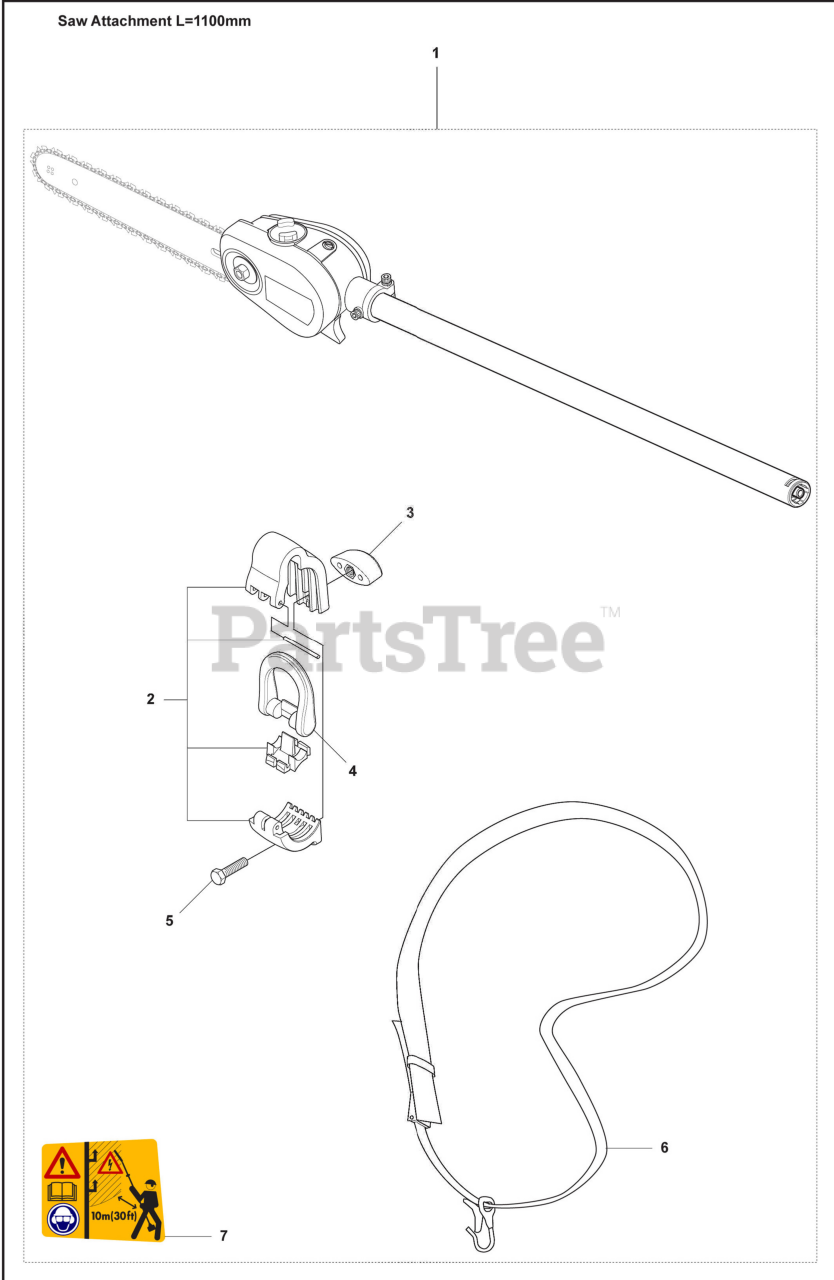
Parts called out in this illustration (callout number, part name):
1	DX POLE SAW ATTACHMEN
1	Dx Pole Saw Attachment
2	Hanging Bracket
5	Screw, M6S 5 X 20
6	Shoulder Strap with Sign
7	Decal
